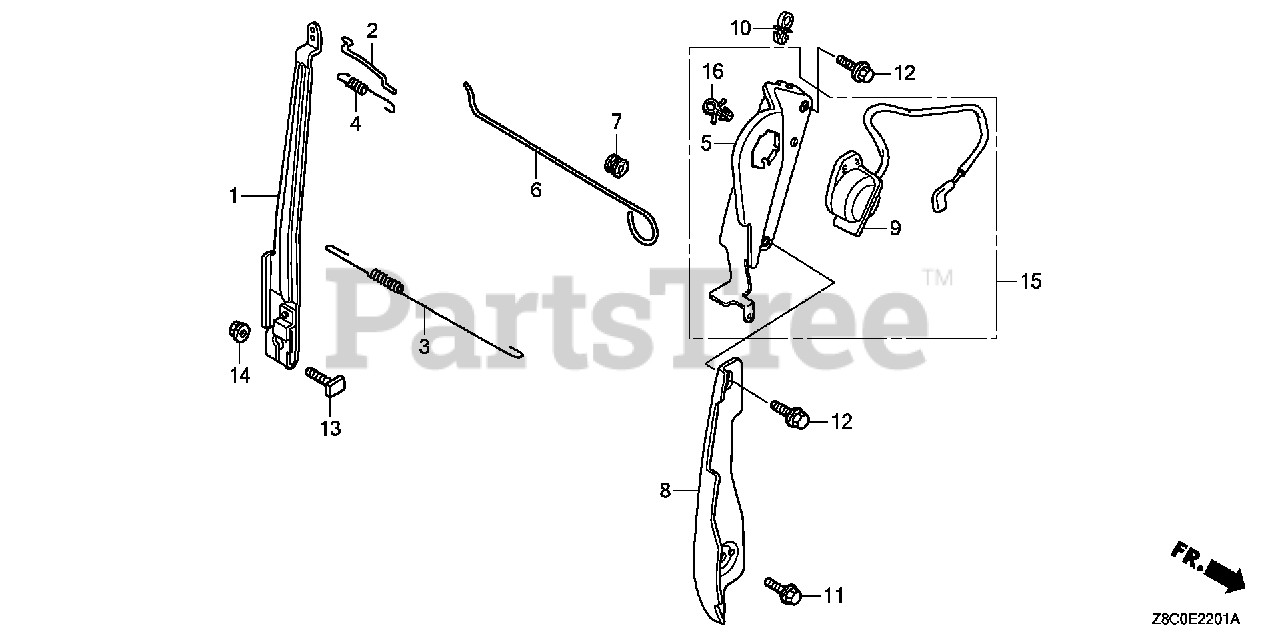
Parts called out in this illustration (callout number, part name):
1	ARM, GOVERNOR
2	ROD, GOVERNOR
3	SPRING, GOVERNOR
4	SPRING, THROTTLE RETURN
5	BASE, CONTROL
6	ROD, CHOKE CONTROL
7	GROMMET, CHOKE ROD
8	PLATE, SIDE
9	SWITCH ASSY., ENGINE STOP
10	HOLDER, WIRE (FASTEX)
10	CLIP A, CABLE (3.8MM BLACK) (NIFCO)
11	BOLT, FLANGE (6X12) (CT200)
12	BOLT, FLANGE (6X14) (CT200)
13	BOLT, GOVERNOR ARM
14	NUT, FLANGE (6MM)
15	CONTROL ASSY.
16	HOLDER, WIRE (FASTEX)
